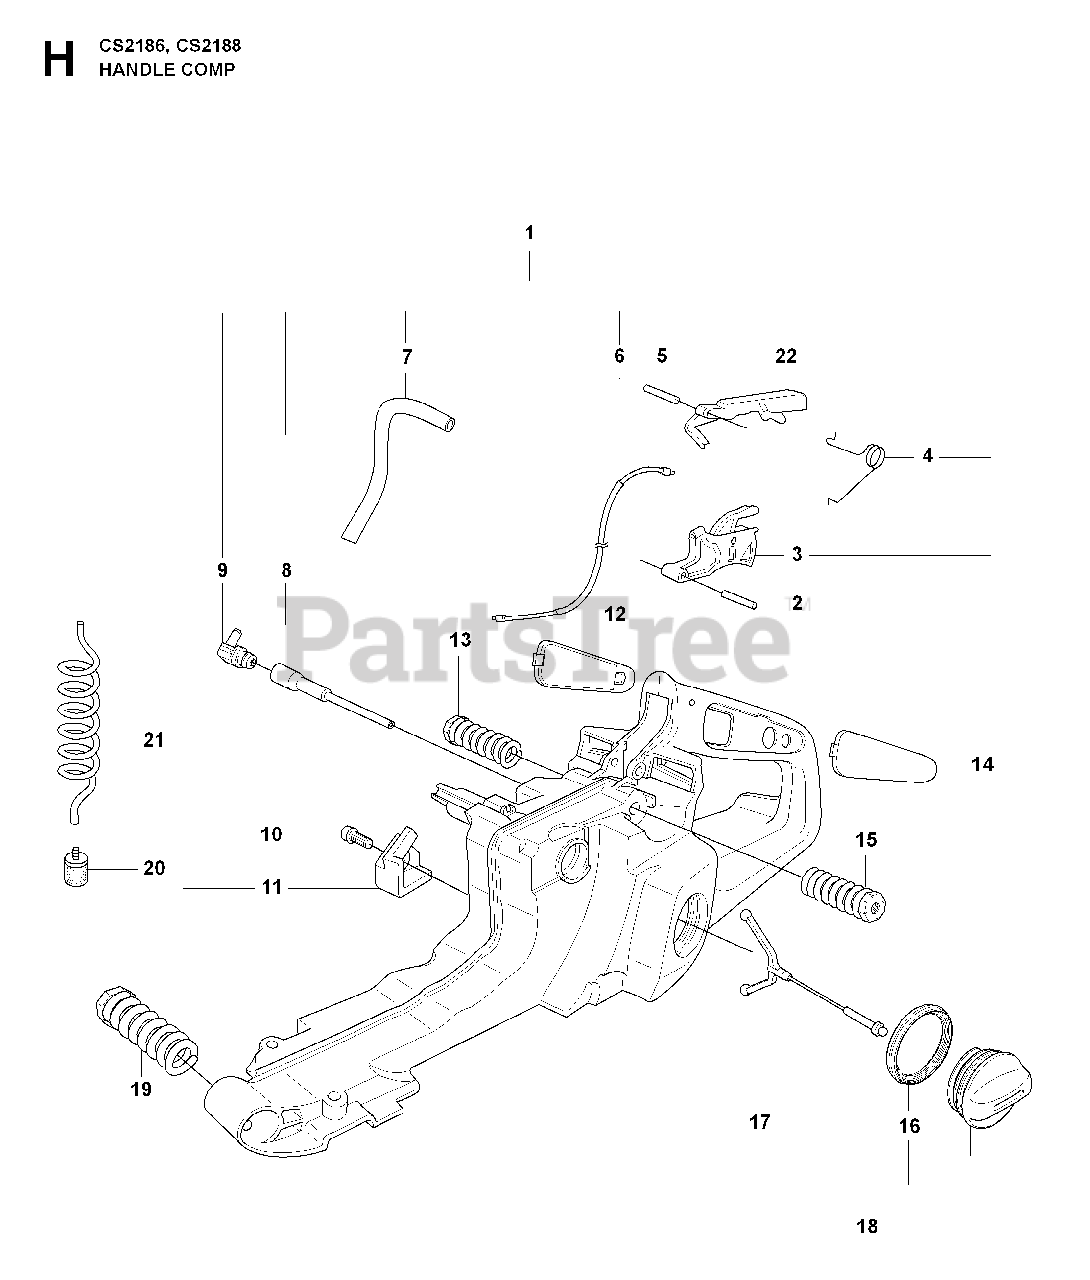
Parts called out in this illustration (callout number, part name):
1	TANK UNIT
2	PIN CPH8 4X20
3	THROTTLE TRIGGER
4	SPRING
5	PIN 3X25
6	WIRE
7	HOSE
8	TANK VALVE
9	CONNECTOR
10	%SCREW
11	PROTECTOR
12	CLUTCH COVER
13	VIBRATION ABSORBER
14	CLUTCH COVER
15	VIBRATION ABSORBER
16	SEALING
17	HOLDER
18	TANK CAP
19	VIBRATION ABSORBER
20	FUEL FILTER
21	FUEL HOSE
22	THROTTLE LOCK
